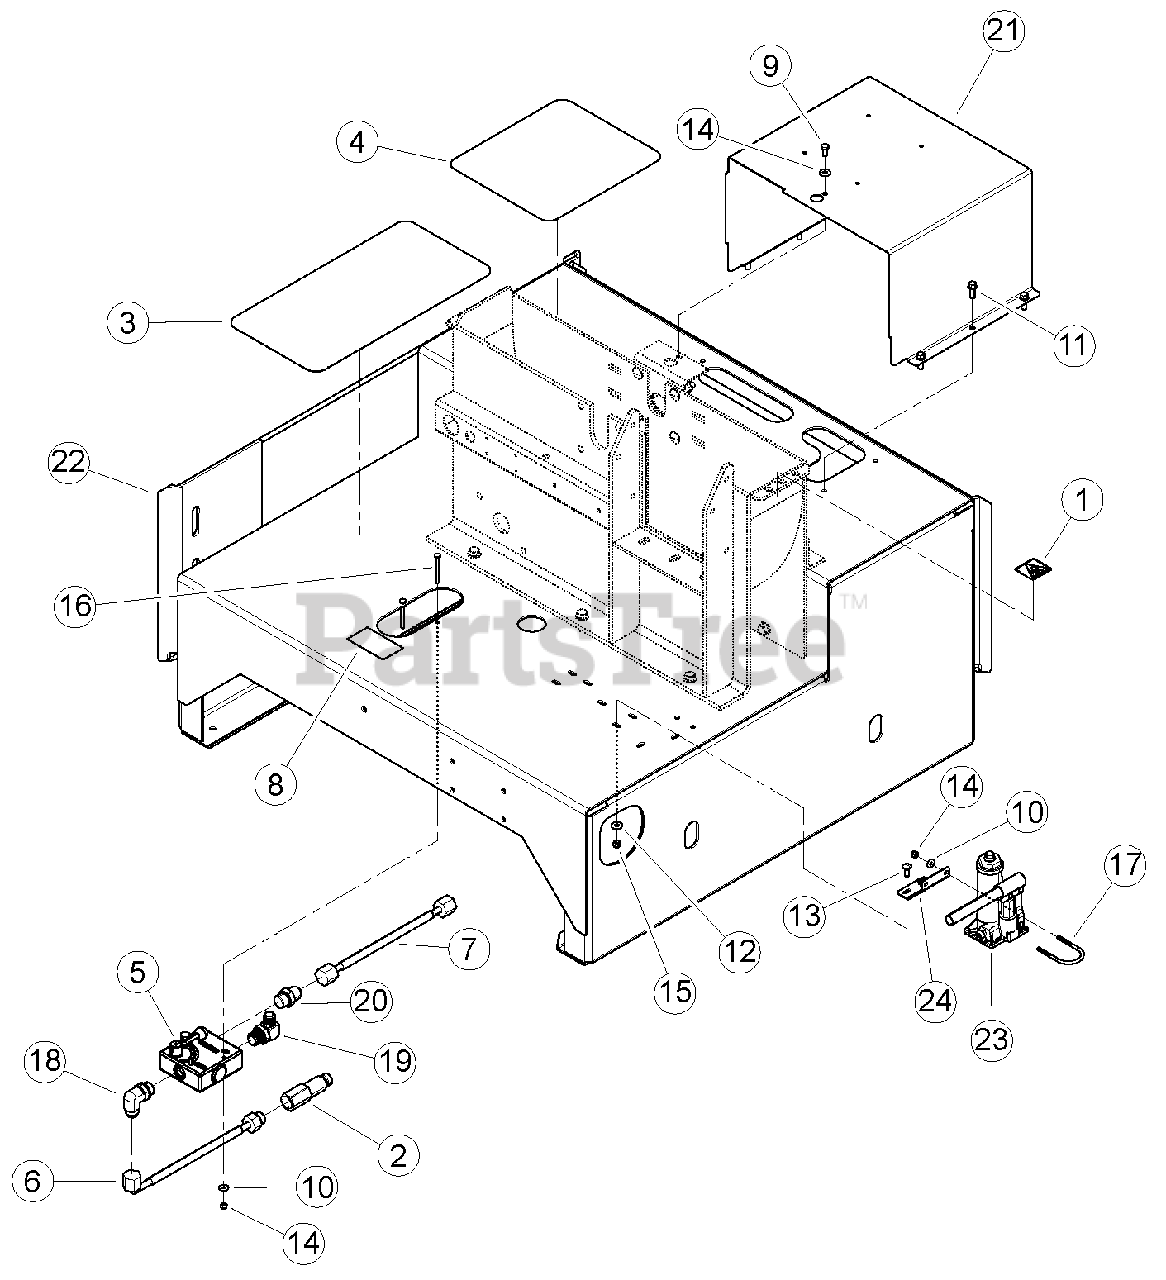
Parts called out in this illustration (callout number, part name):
1	DECAL, SHIELD DANGER ISO
3	TREAD, SAFETY
4	TREAD, SAFETY
5	VALVE, 30 GPM FLOW CONTROL
6	HOSE, .75 X 119 -12 MORING / -12 FMJIC 90 DEG.
7	HOSE, .75 X 40 -12 FMJIC / -12 FMJIC
8	DECAL, FEED SPEED
10	WASHER, 1/4 FLAT ZP
11	SCREW, 3/8-16 X 1 LG THD CUTT ZP
12	WASHER, 5/16 FLAT ZP
13	BOLT, 5/16 X 7/8 CRG GR5 NC ZP
14	NUT, 1/4 NE NYLOCK ZP
15	NUT, 5/16 NE NYLOCK ZP
16	BOLT, 1/4 X 2-1/2 HEX HD GR5 ZP
17	U-BOLT, 1/4 X 1-1/2 PIPE
18	ADAPTER, -12 MORING / -12 MJIC 90 DEG.
19	ADAPTER, -12 MORING / -10 MJIC 90 DEG.
20	ADAPTER, -12 MORING / -12 MJIC
21	COVER, HYDRAULIC MOTOR (CH500H)
22	WELDMENT, CHIPPER BASE
23	JACK, HYDRAULIC 2 TON
24	PLATE, JACK MOUNT
